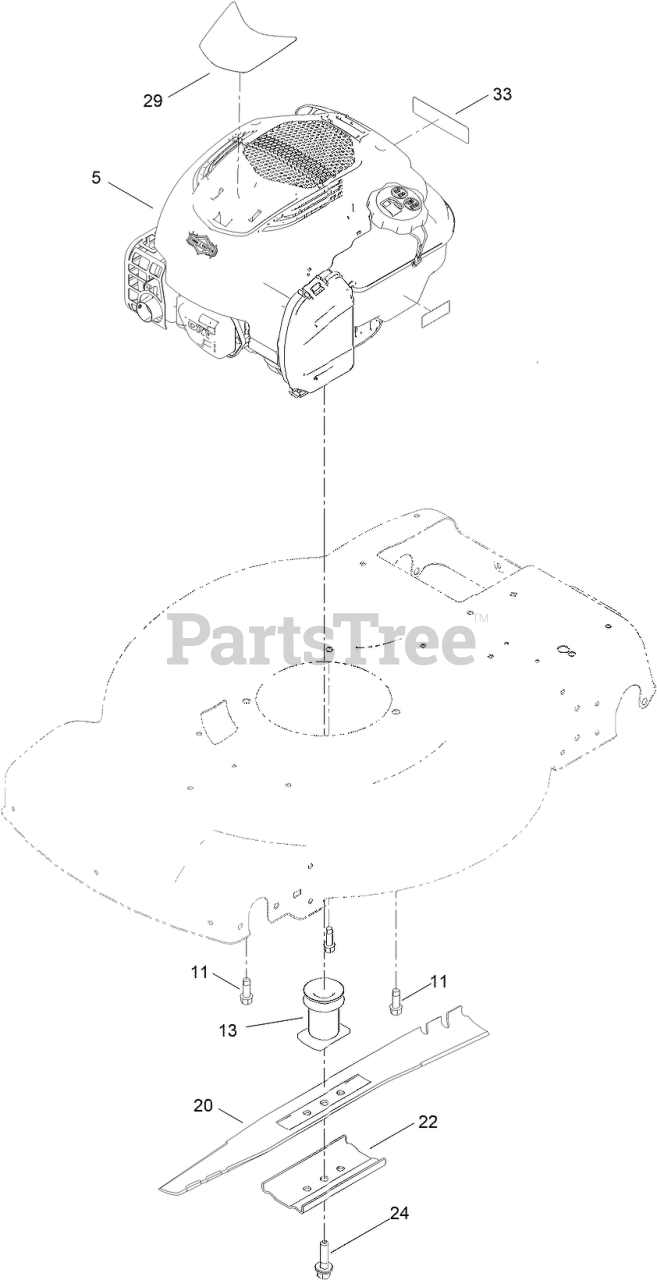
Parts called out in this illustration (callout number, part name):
5	ENGINE-BRIGGS, 625 EXI ES
11	SCREW-THD FORM, HWH
13	DRIVER-BLADE
20	BLADE-22 INCH
22	SUPPORT-BLADE
24	BOLT-BLADE
29	DECAL - BRIGGS 625 EX ES
33	DECAL-ARRESTOR, SPARK
